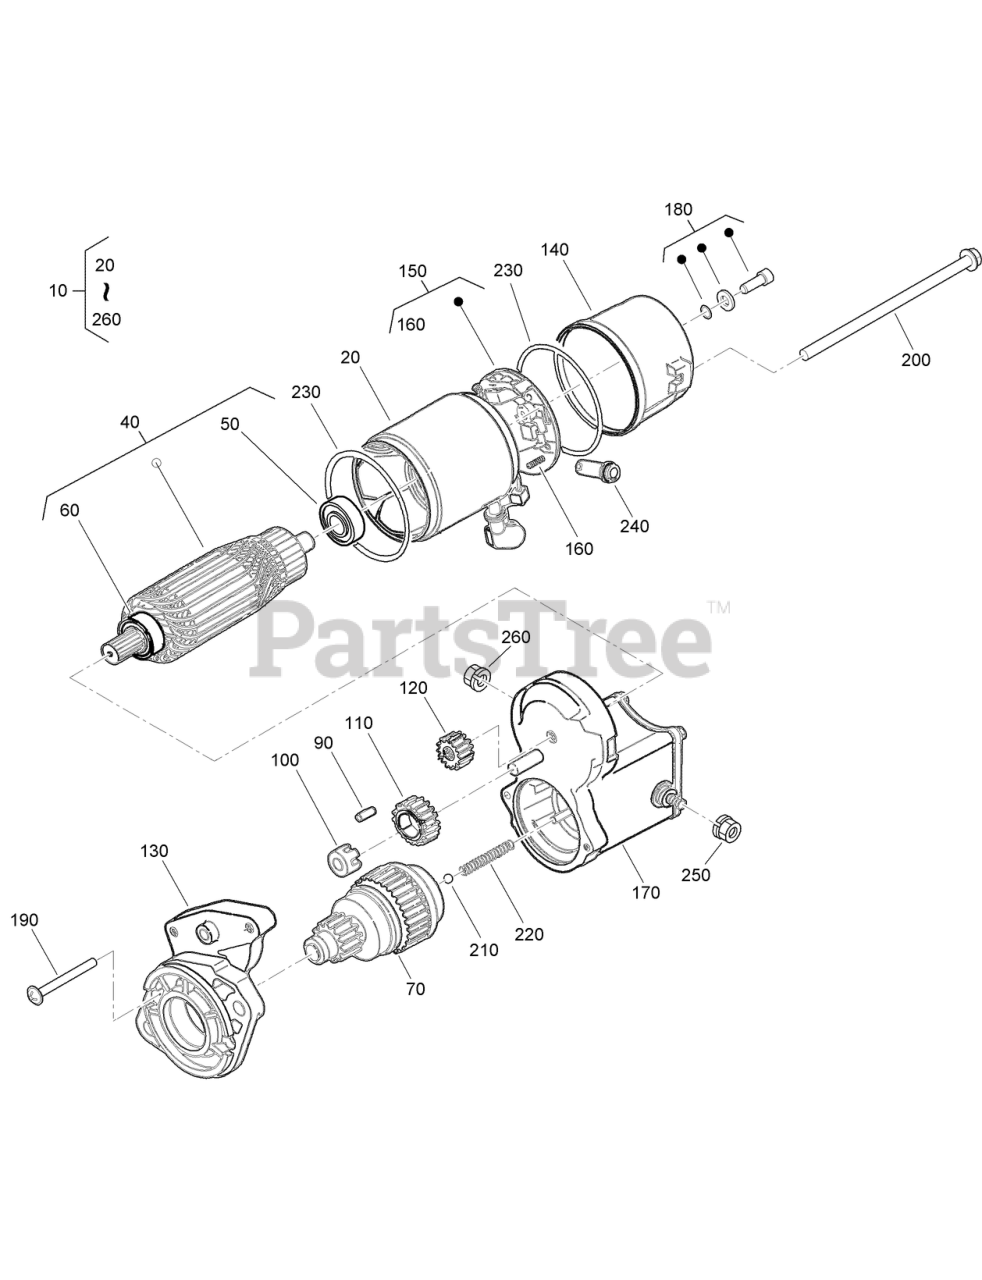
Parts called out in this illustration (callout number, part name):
10	STARTER ASM
40	ARMATURE
50	BEARING
60	BEARING
70	CLUTCH-RUNNING, OVER
90	ROLLER
100	RETAINER
130	FRAME-END, DRIVE
140	FRAME-END
150	HOLDER-BRUSH
160	SPRING
170	MAGNETIC SWITCH ASM
200	BOLT-THROUGH
220	SPRING
230	O-RING
240	PIPE-DRAIN
250	NUT-HEXAGON
260	NUT-HEX
